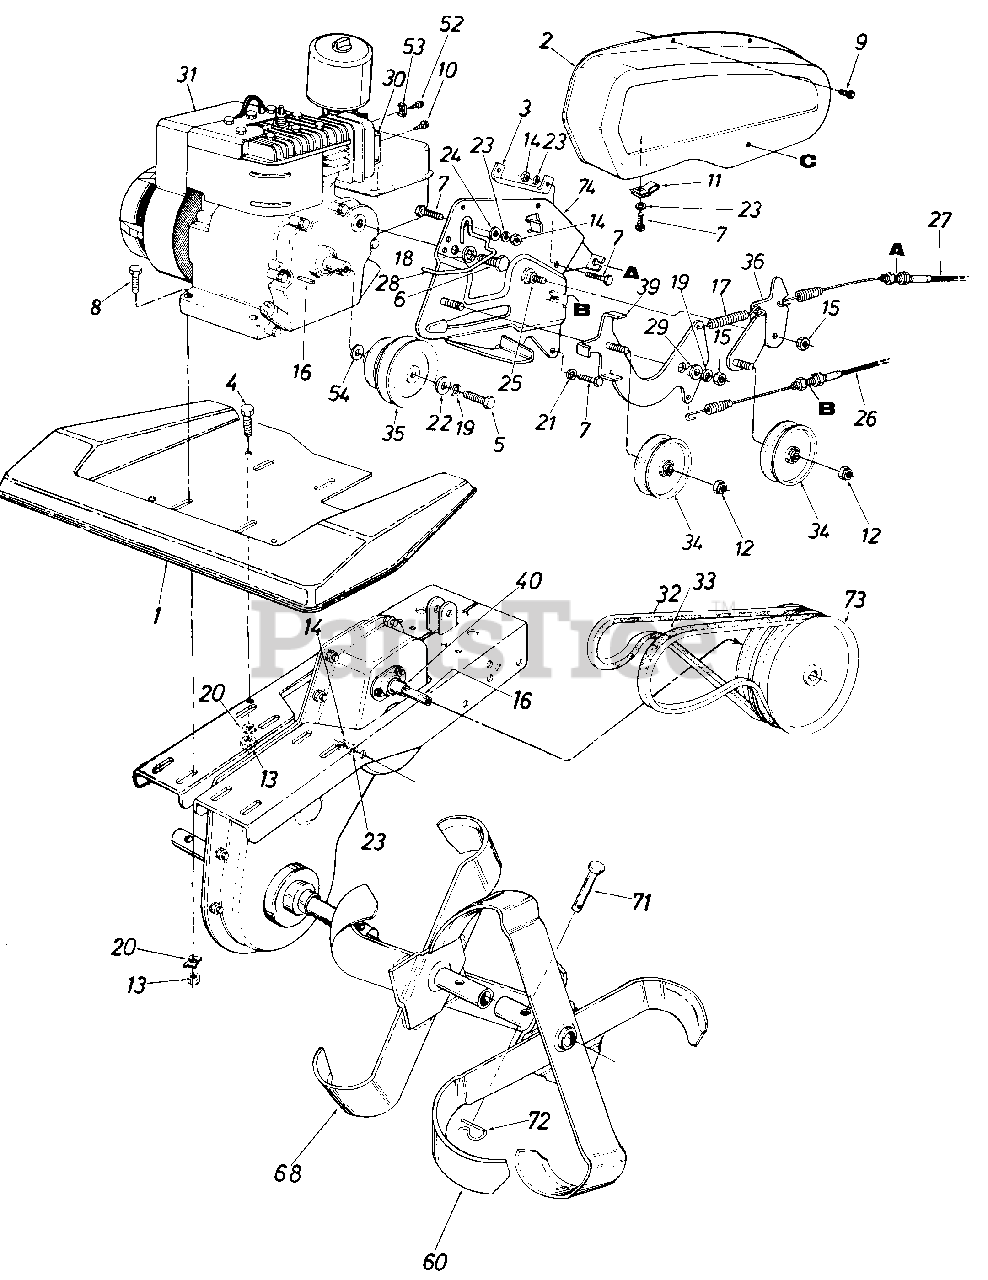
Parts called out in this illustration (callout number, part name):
4	Hex Bolt 5/16-18 x .75" Lg.*
5	Hex Bolt 3/8-24 x 1.25" Lg.*
6	Hex Bolt 5/16-24 x .62" Lg.*
7	Hex Bolt 1/4-20 x .85" Lg.*
8	Hex Bolt 5/16-18 x 1.5" Lg.*
9	Hex Wash. Hd. Tap Scr. 1/4-20 x .5" Lg.
10	Hex Wash. Hd. Slotted Scr. #8-32 x .38"
11	Speed Nut 1/4-20 Thd.
12	Hex L-Nut 3/8-24 Thd.
13	Hex Nut 5/16-18 Thd.*
14	Hex Nut 1/4-20 Thd.*
15	Hex L-Nut 3/8-16 Thd.
16	Sq. Key 3/16 x 1.5" Lg.
17	Extension Spring 2.03 Lg.
18	L-Wash. 5/16" I.D.*
19	L-Wash. 3/8" I.D.*
20	Spec. L-Wash. 5/16" I.D.
21	Spr. Wash. .265" I.D. x .562" O.D.
22	Fl-Wash. 3/8" I.D. x 1" O.D. x 1.27"
23	L-Wash. 1/4" I.D.*
24	Fl-Wash. .25 I.D. x .62 O.D.
25	Shld. Bolt .625 Dia. x .170 Lg.
26	Clutch Control Cable
27	Clutch Control Cable
28	Belt Guard Rod
29	Shld. Spacer .380 I.D.
30	Muffler Deflector
31	Engine
32	V-Belt
33	V-Belt
34	Fl-Idler w/Flanges 3.12 O.D. x .75
35	Engine Pulley
36	Idler Brkt. Ass'y.
39	Reverse Idler Brkt. Ass'y.
40	Spacer .635 I.D.
52	Hex Sems Scr. #10-32 x .62" Lg.
53	Casing Clamp
54	Fl-Wash. .75" I.D. x 1.5" O.D. x .12"
72	Intern. Cotter Pin
73	Transmission Pulley 6" Dia.
74	Clutch Mtg. Plate Ass'y.
